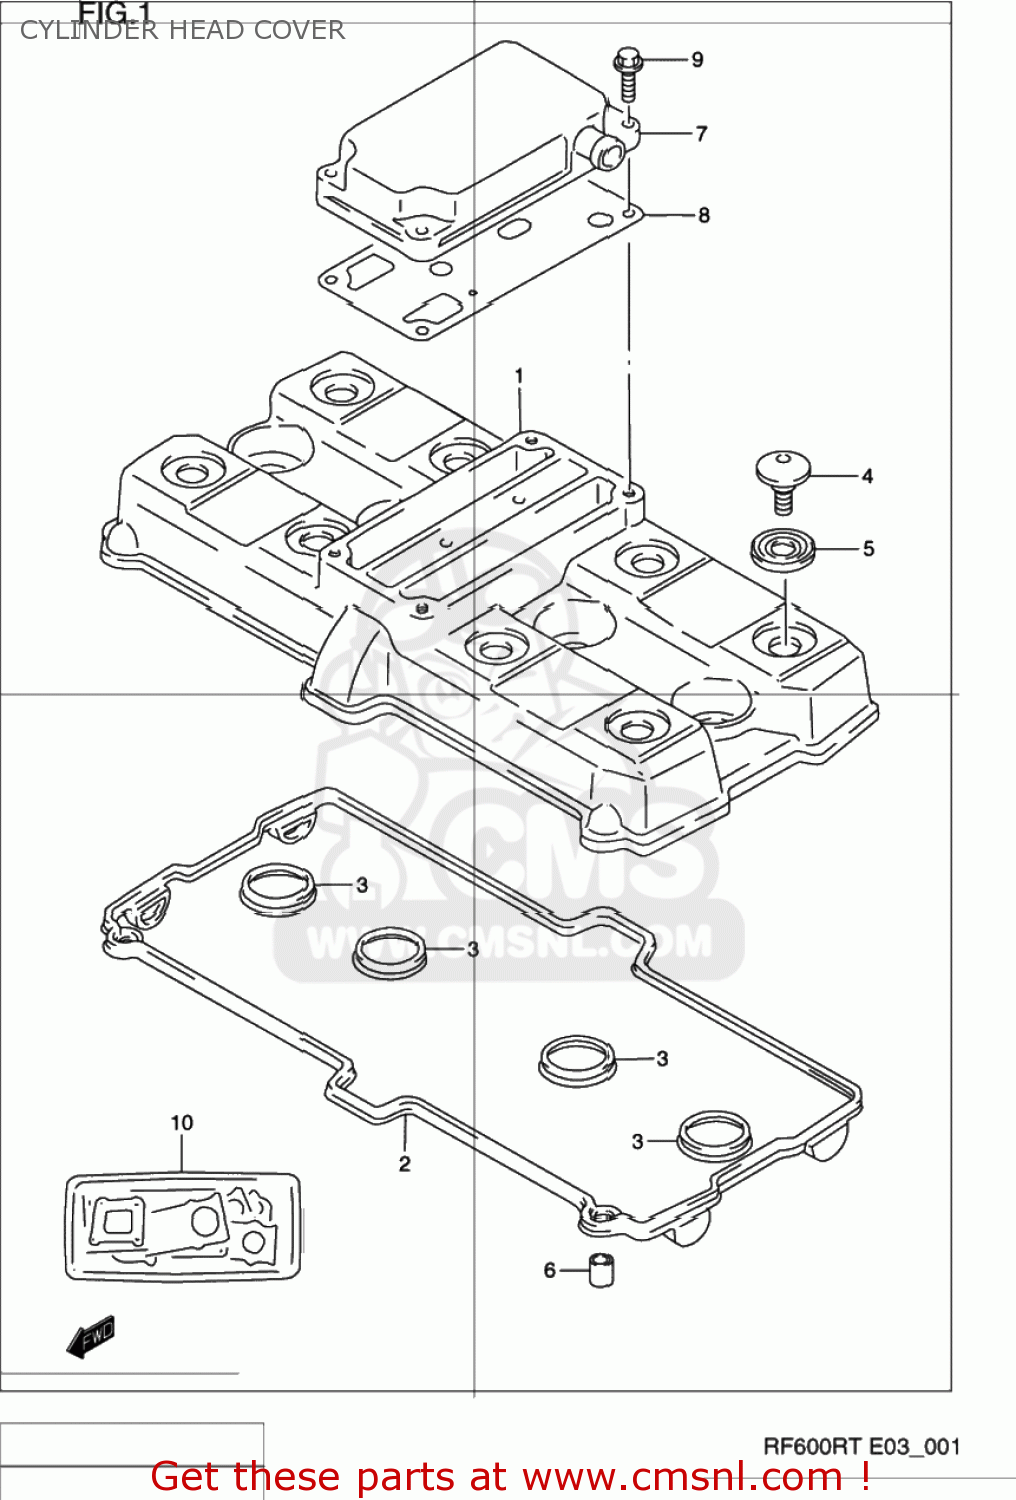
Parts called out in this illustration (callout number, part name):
1	COVER,CYLINDER HEAD
2	GASKET,CYL HEAD COVER NO.1
3	GASKET,CYL HEAD COVER NO.2
4	BOLT(7X17.5)
5	WASHER(10.6X25.5X2.3)
6	PIN(6.2X8X11)
7	COVER,BREATHER
8	GASKET,BREATHER COVER
9	BOLT
10	GASKET SET (NAS)
